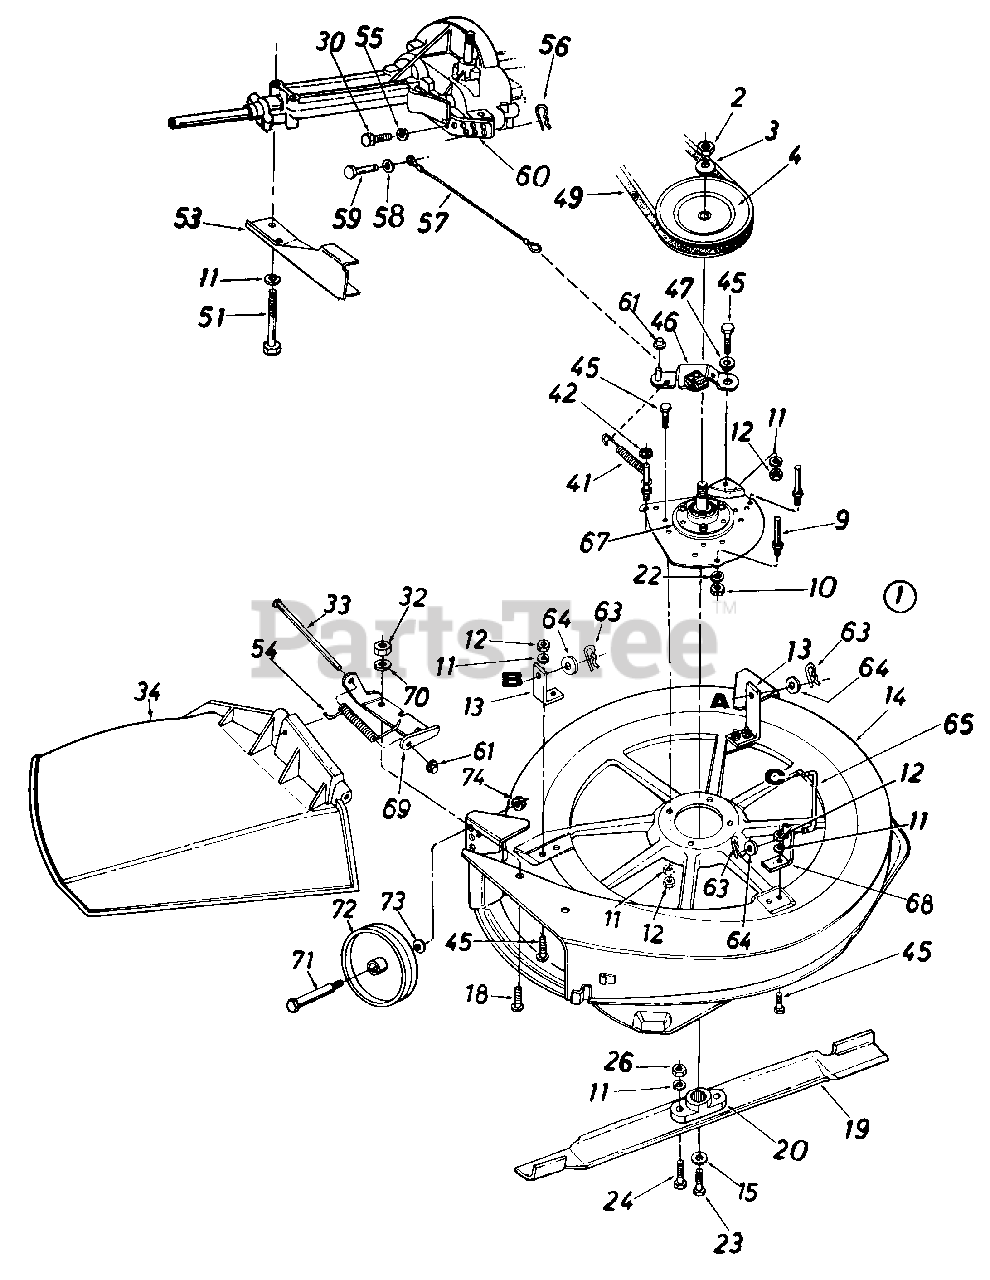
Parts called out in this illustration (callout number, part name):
3	Bell-Wash. .630" I.D. x 1.25"
4	5/8 V-Pulley .75" I.D. x 7"
9	Stud 3/8-16 x 2.75" Lg.
10	Hex Jam Nut 3/8-16 Thd.
11	L-Wash. 5116" I.D.
12	Hex Nut 5/16-18 Thd.
18	Hex Bolt 1/4-20 x .62" Lg.
19	30" High Lift Blade
20	Blade Adapter
22	L-Wash. 3/8" I.D.
23	Hex Bolt 3/8-24 x 1.0
24	Hex Bolt 5/16-24 x 1.0" Lg.
26	Hex Nut 5/16-24 Thd.*
30	Hex Bolt 1/4-20 x .50" Lg.
32	Hex Nut 1/4-20 Thd.
33	Hinge Pin
34	Chute Ass'y. Comp.
41	Extension Spring
42	Push Speed Nut
45	Hex Bolt 5/16-18 x .75"
46	Blade Brake Brkt. Ass'y.
47	Shoulder Spacer .500" Dia.
49	"V"-Belt
51	Hex Bolt 5/16-18 x 2.75"
55	L-Wash. 1/4" I.D.
56	Int. Cot. Pin 5/16" Dia.
57	Brake Cable 9.75" Lg.
58	Fl-Wash. .281" I.D. x .50"
59	Clevis Pin 1/4" Dia.
60	Lower Inside Belt Guard
61	Cap Speed Nut 1/4" Rod
63	Int. Cotter Pin 1/2" Dia.
64	Fl-Wash. .531" I.D. x .930"
65	Deck Link 3.9" Lg.
67	Blade Spindle Ass'y. Comp.
68	Weld Bracket
69	Hinge Mtg. Brkt.
70	Bell-Wash. 1/4" I.D.
71	Shld. Scr. .498" x 1.53" Lg.
72	Deck Wheel
73	Bell-Wash. .38" I.D. x .88"
74	Hex L-Nut 3/8-16 Thd.
